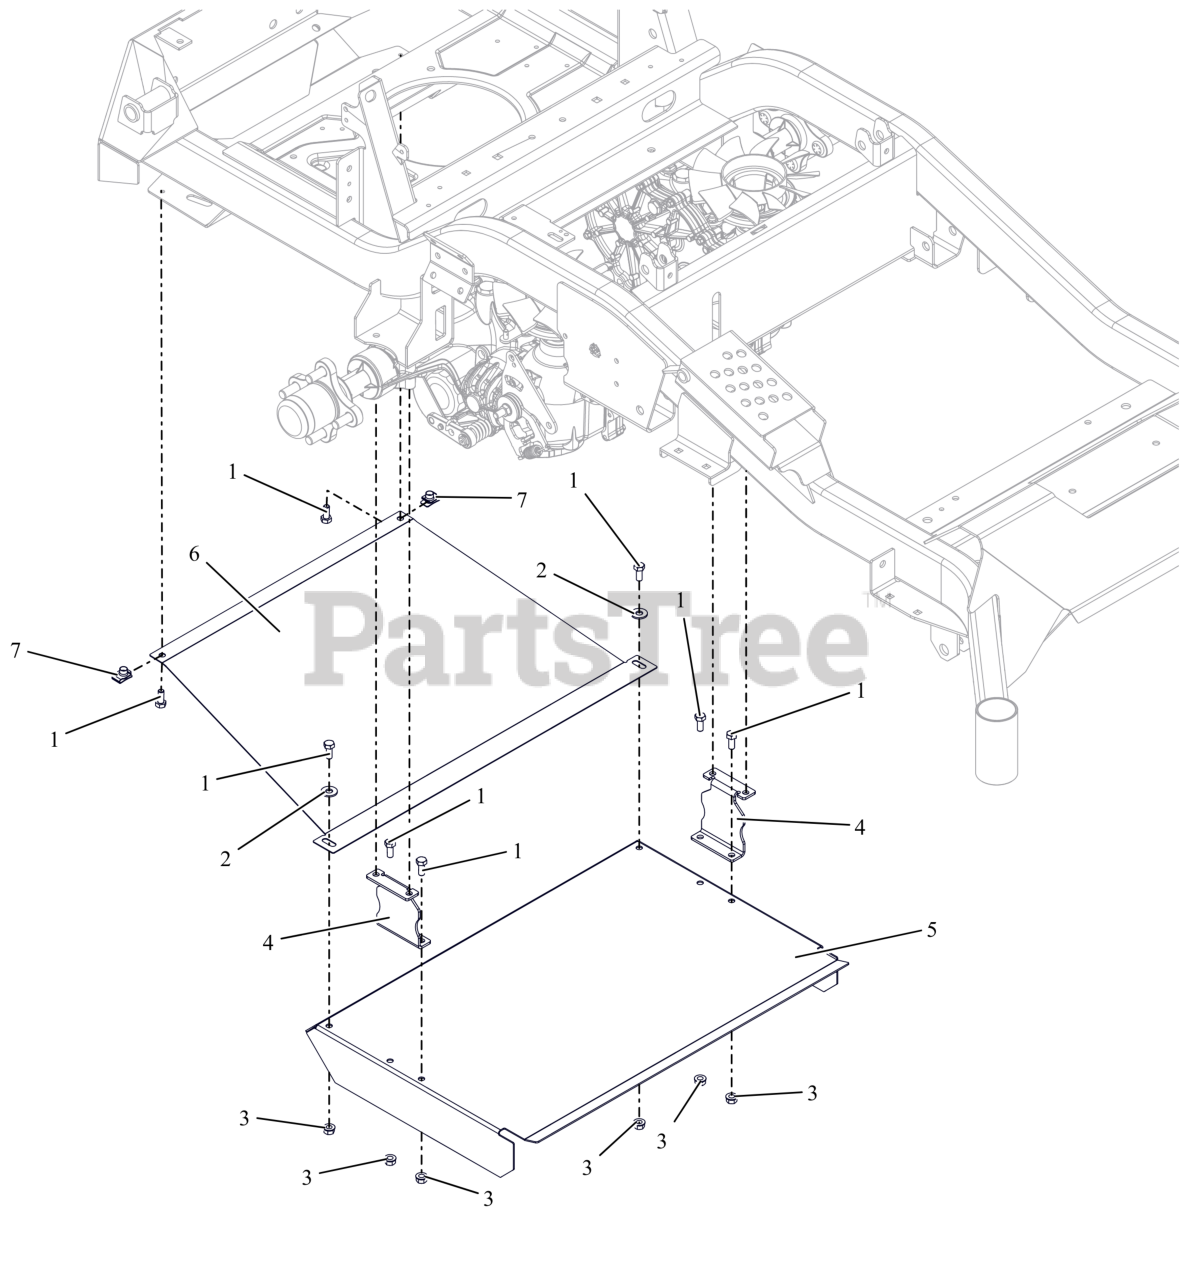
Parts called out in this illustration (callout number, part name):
1	BLT,HEX .31-18X.75 G5 ZCC
2	WSHR,FLT .375X.875X.083 ZCC
3	NUT,LK-CTR-FLG .31-18 GF ZCC
4	BRKT, DEFLECTOR SUPPORT
5	DEFLECTOR- TRANSAXLE
6	DEFLECTOR, UNDERBODY
7	NUT-CLIP RETAINER 5/16-18X.56
